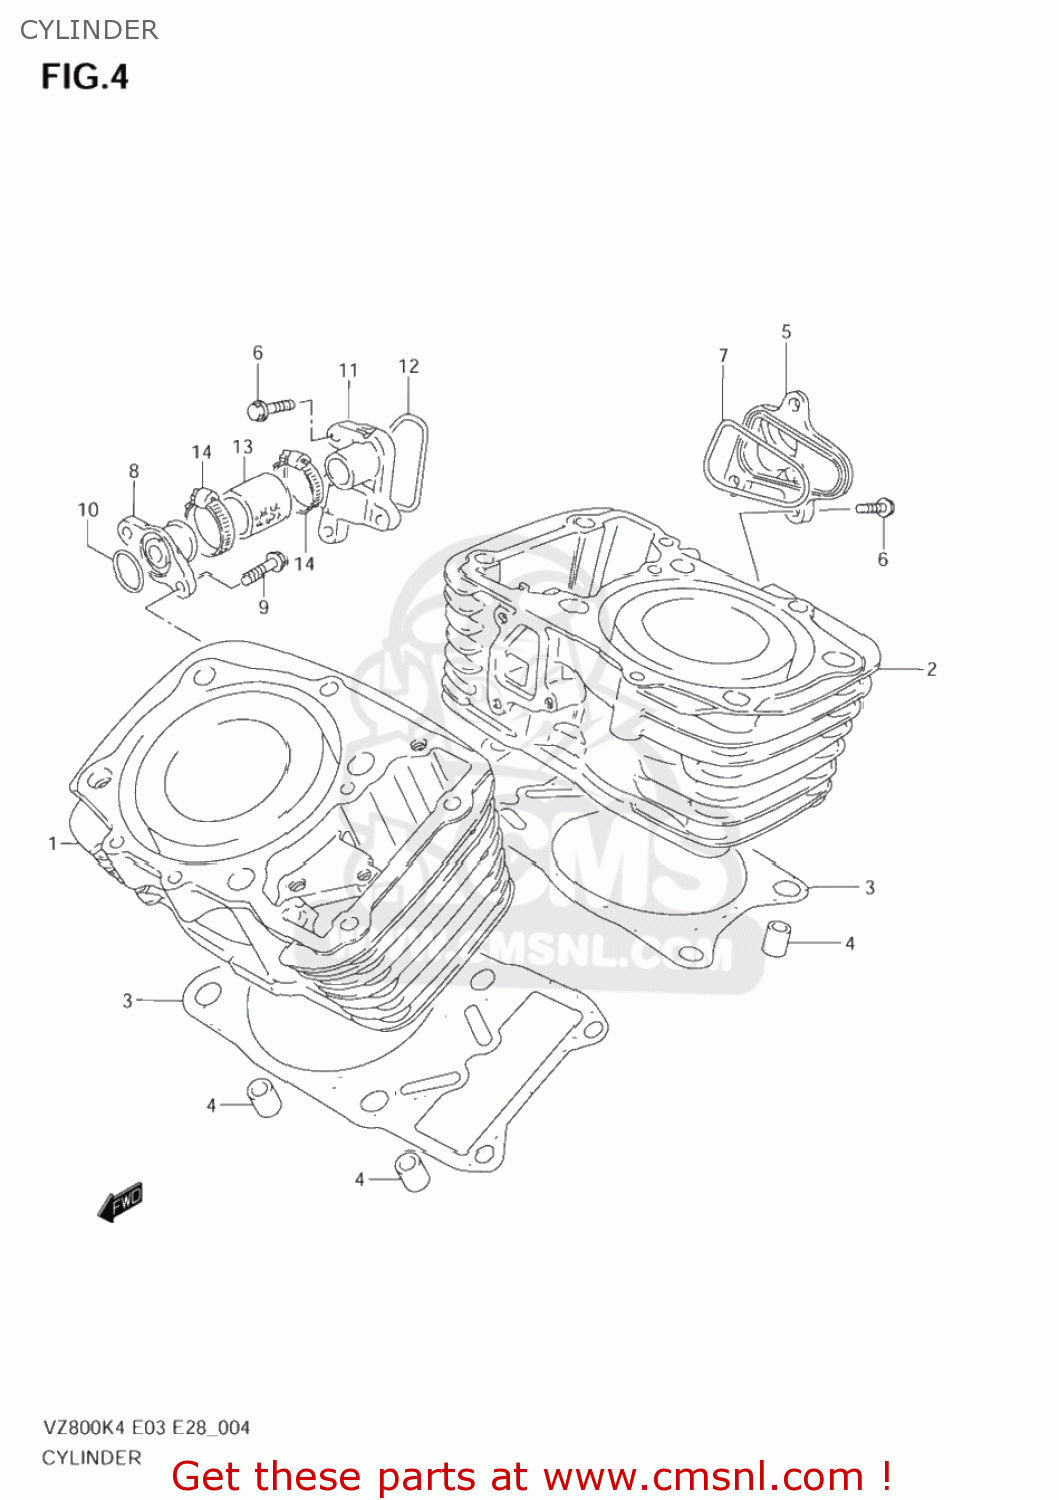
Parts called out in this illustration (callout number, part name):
1	CYLINDER,FR
2	CYLINDER,RR
3	GASKET,CYLINDER (NAS)
4	PIN
5	CHAMBER,WATER INLET
6	SCREW
7	O RING,INLET WATER CHAMBER
8	UNION,WATER INLET
9	BOLT
10	O RING(D:2.4,ID:15.8)
11	CHAMBER,WATER OUTLET
12	O RING,OUTLET WATER CHAMBER
13	HOSE,RADIATOR INLET
14	CLAMP
